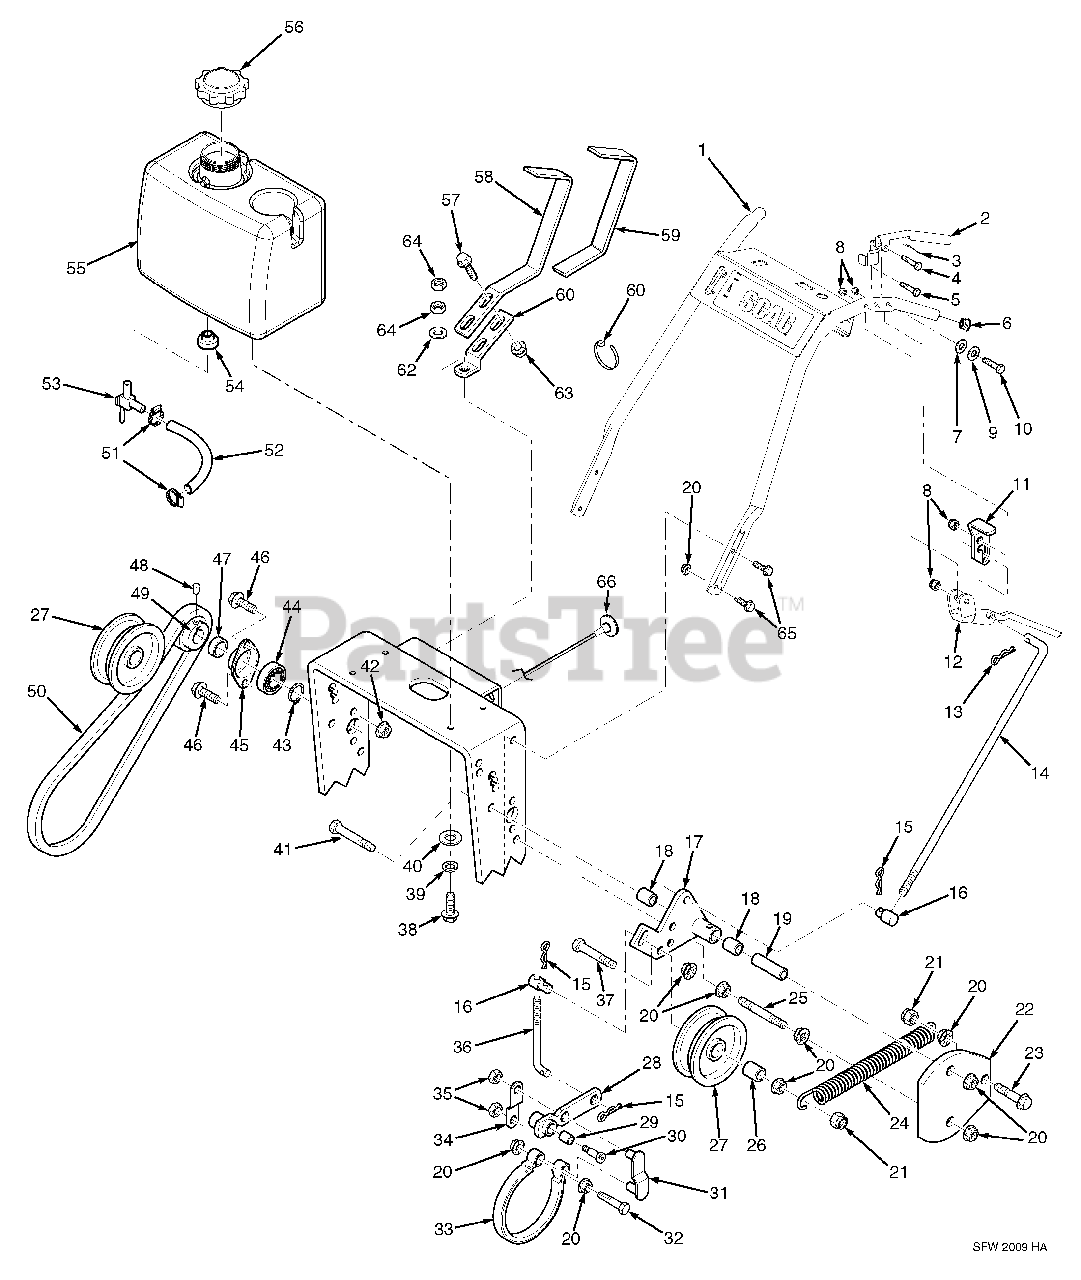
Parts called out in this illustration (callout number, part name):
1	Handle Weldment w/Decals
2	Operator Presence Handle, LH
3	Spring, Operator Presence
4	Bolt, Hex Head 5/16-18 x 2-3/4"
5	Bolt, Hex Head 5/16-18 x 2-1/2"
6	Plug, Handle Bar
7	Washer, Curved Spring
8	Nut, Elastic Stop 5/16-18
9	Flatwasher, 5/16-.375 x .875 x .083
10	Bolt, Hex Head 5/16-18 x 2"
11	Neutral Latch Assembly, LH
12	Lever, Steering Brake
13	Hair Pin Cotter
14	Rod, Steering Control
15	Hair Pin Cotter
16	Swivel Joint
17	Idler Bracket Assembly, RH
18	Bearing
19	Sleeve
20	Nut, Serrated Flange 3/8-16
21	Nut, Elastic Stop 3/8-16
22	Belt Guard
23	Bolt, Serrated Flange 3/8-16 x 1-1/4"
24	Spring
25	Stud, 3/8-16 x 5"
26	Spacer
27	Pulley, Idler 5"
28	Lever Weldment, Brake w/Bearing
29	Bearing
30	Bolt, Shoulder 1/2 x 1"
31	Link Weldment, Brake
32	Bolt, Hex Head 3/8-16 x 2"
33	Brake Band Assembly
34	Link, Brake
35	Nut, Push-On
36	Rod, Brake
37	Bolt, Hex Head 3/8-16 x 3-1/4"
38	Bolt, Hex Head 5/16-18 x 1"
39	Lockwasher, 5/16" Spring
40	Flatwasher, 5/16-.375 x .875 x .083
41	Bolt, Hex Head 3/8-16 x 4-1/2"
42	Nut, Serrated Flange 1/4-20
43	Retaining Ring, 5/8" Ext.
44	Bearing, Jackshaft
45	Flange, Jackshaft Bearing
46	Bolt, Serrated Flange 1/4-20 x 3/4"
47	Spacer, Jackshaft
48	Set Screw, Hex Socket 5/16-18
49	Pulley, Jackshaft 3.25 OD x .625 Bore
50	Belt, Wheel Drive
51	Clamp, 1/4" ID Fuel Hose
52	Fuel Hose, 1/4" ID
53	Valve, Fuel Shutoff w/Screen
54	Bushing, .56 Dia. Viton
55	Fuel Tank Assembly
56	Cap, Fuel Tank
57	Bolt, Serrated Flange 5/16-18 x 1"
58	Shift Lever Extension w/Grip
59	Grip, Shift Handle
60	Cable Tie
61	Shift Lever
62	Flatwasher, 3/8-.391 x .938 x .105
63	Nut, Serrated Flange 5/16-18
64	Nut, 3/8-24 UNF
65	Bolt, Serrated Flange 3/8-16 x 1"
66	Choke Control
